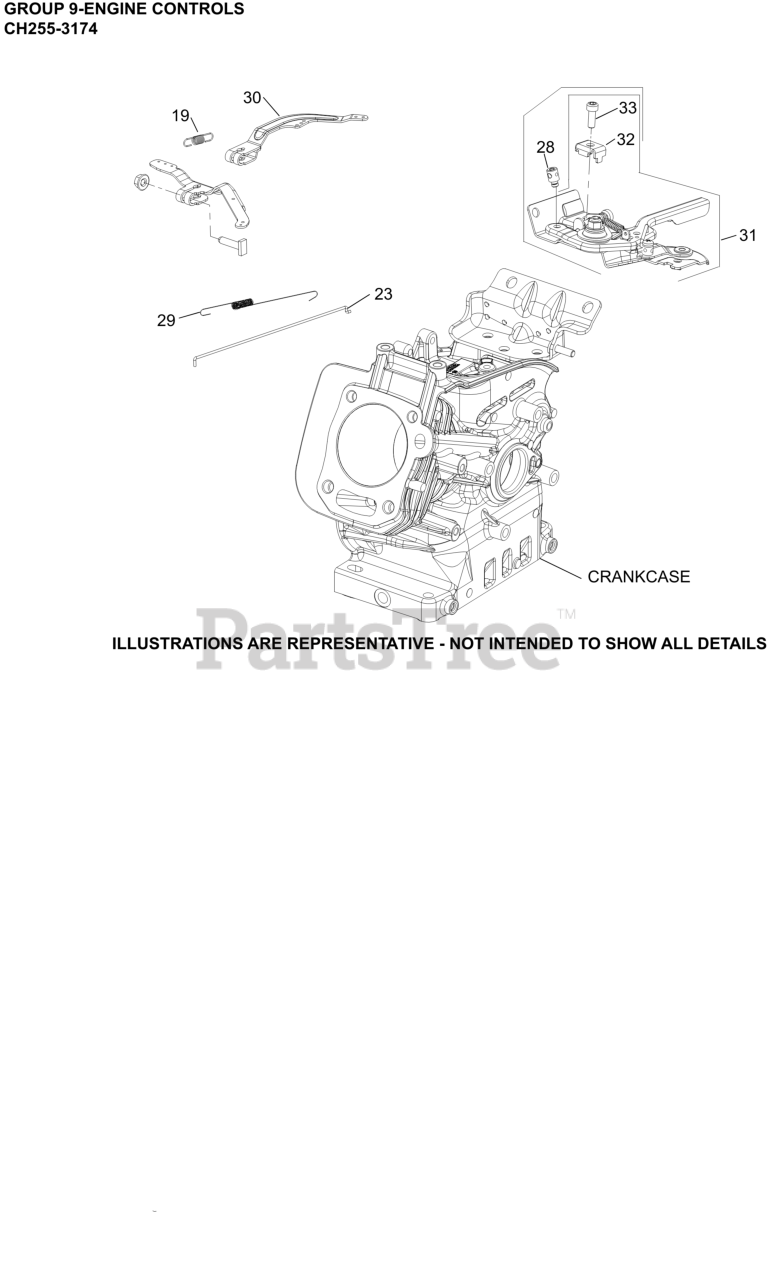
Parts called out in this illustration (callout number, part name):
19	SPRING, GOVERNOR
23	LINKAGE, GOVERNOR-USE 18 079 05-S
28	KIT, CABLE CLAMP
29	SPRING, LINKAGE
30	KIT, GOVERNOR LEVER
31	VARIABLE SPEED CONTROL ASSEMBLY
32	CLAMP, CABLE
